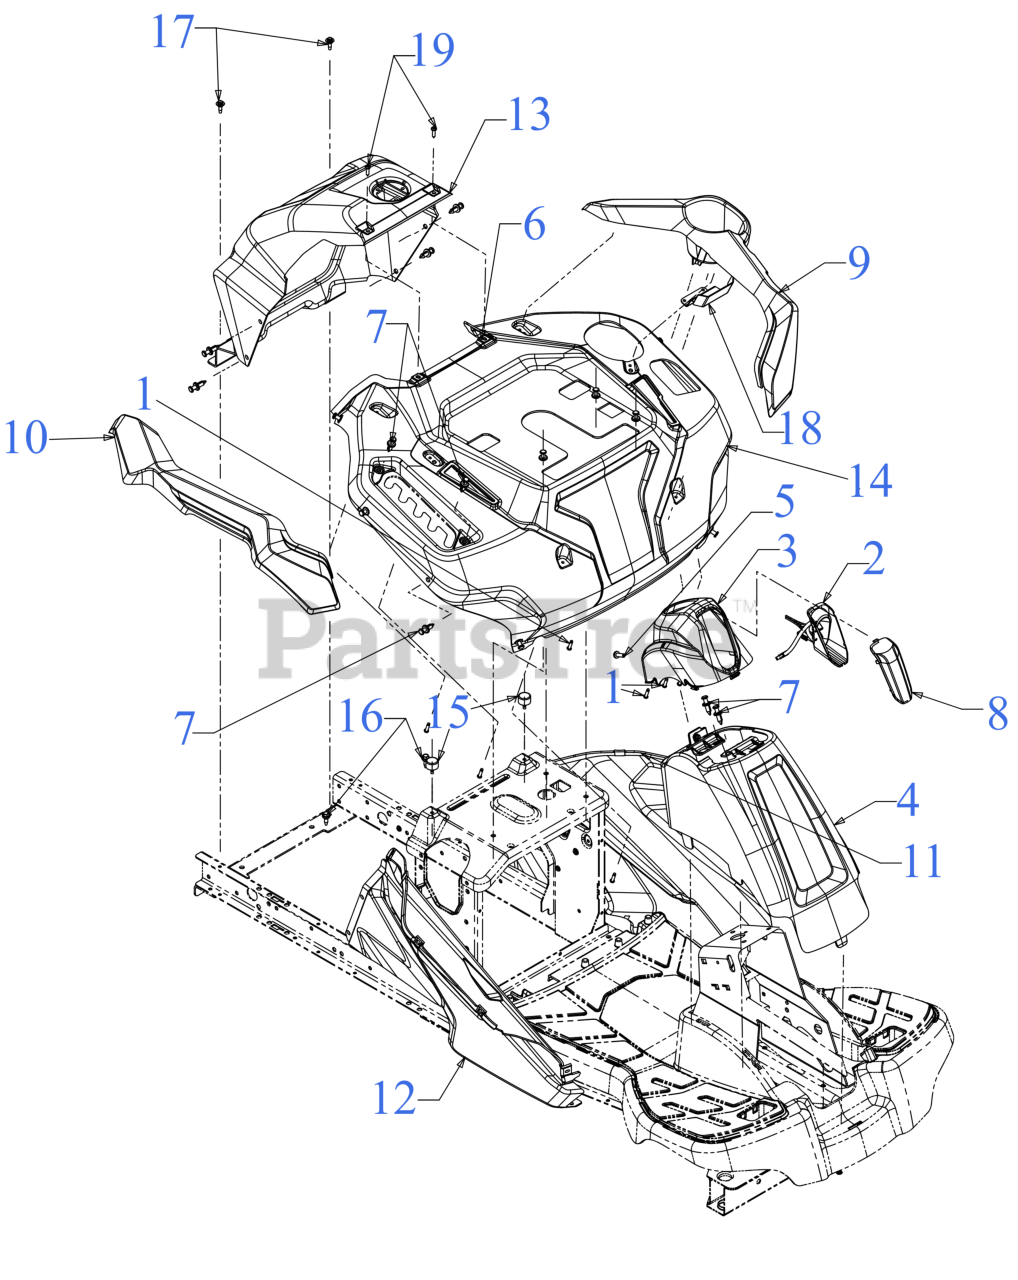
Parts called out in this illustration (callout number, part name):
1	SCREW, #8-16X.750 PH
2	LED HEADLIGHT HARNESS ASSEMBLY
3	COLUMN CAP (LIBERTY RED)
4	COLUMN COVER (LIBERTY RED)
5	SCREW 1/4-20X.75
6	U-NUT #10-16
7	PLASTIC RIVET
8	LED HEADLIGHT LENS
9	FENDER TRIM (LH) (LIBERTY RED)
10	FENDER TRIM (RH) (LIBERTY RED)
11	BODY PANEL (LH)
12	BODY PANEL (RH)
13	BODY COVER (REAR)
14	FENDER
15	BUMPER .62 DIA x .50
16	SHOULDER SCREW
17	SHOULDER SCREW M6-1 .368 X.115
18	FENDER BRACKET
19	SCREW:10-6 x .75
